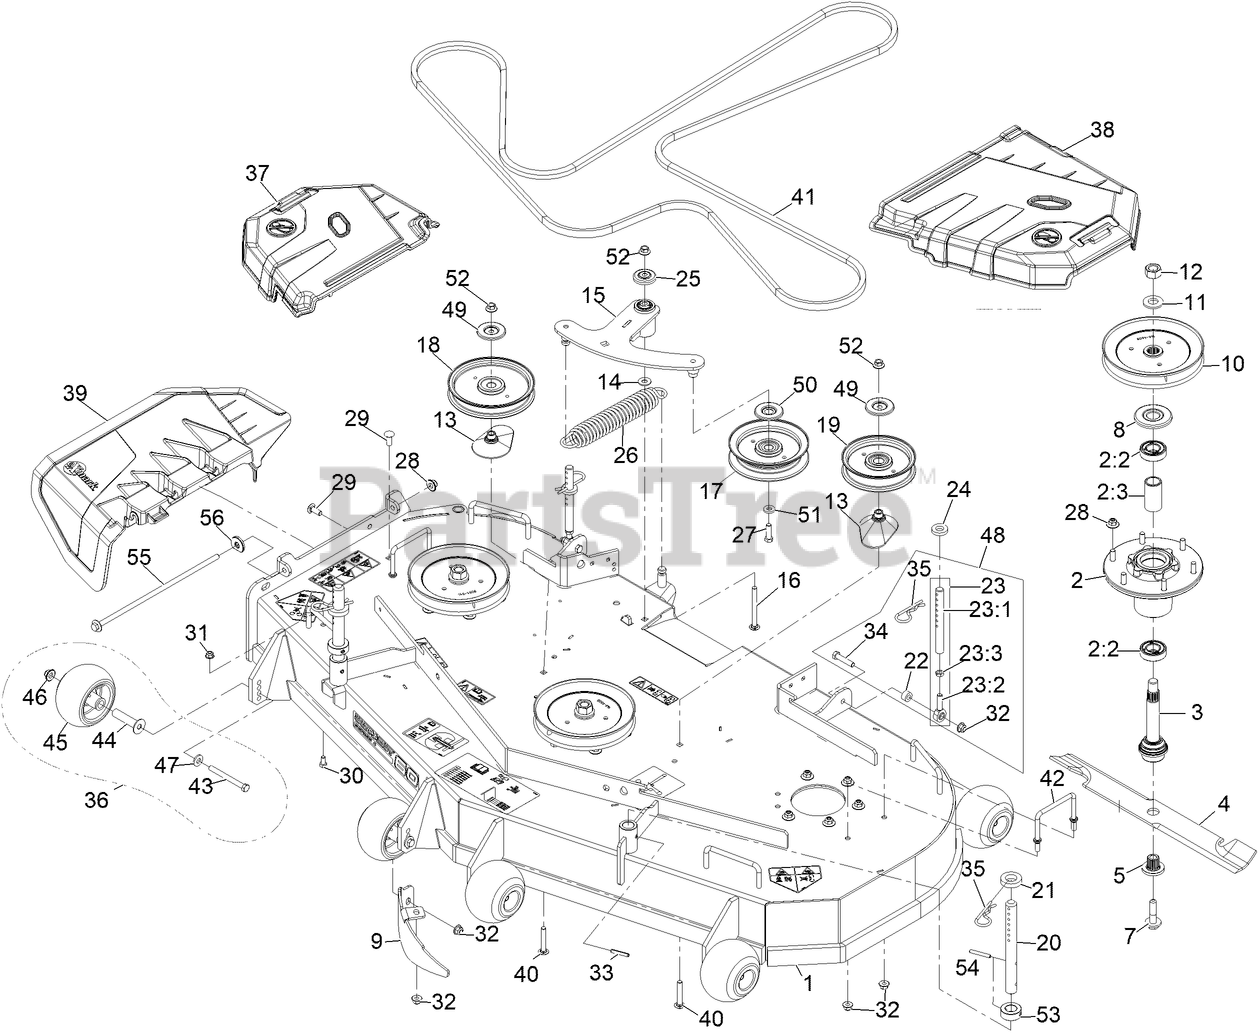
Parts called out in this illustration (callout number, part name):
1	ASM, Deck W/ Decals, 60"
2	ASM-CUTTER HSG WITH BEARINGS
2:2	BEARING-BALL
2:3	SPACER-BEARING
3	ASM-SPINDLE AND SEAL
4	Blade-Extreme 2, 20.50"
5	BUSHING,SPLINED
7	SCREW,SEMS 1/2-20 X 2.19
8	GUARD,BEARING TOP .989
9	DOGLEG - LZ60
10	SHEAVE,BLADE DRIVE 7.25
12	NUT-HEX
13	SPACER-PULLEY
14	WASHER-FLAT
15	ASM, DECK IDLER
16	SCREW-CARR
17	IDLER-PULLEY, FLAT
18	Idler-Pulley, Flat
19	Pulley-Idler, Flat
20	ROD, DECK SUPPORT
21	SPACER-DECK SUPPORT
23:1	LINK,SUPPORT
23:2	BALLJOINT
23:3	NUT-HJ
25	GUARD-TOP
26	SPRING-EXTENSION
27	SCREW-HH
28	Nut-Nyloc 3/8-16 Flg
29	SCREW-CARR
30	SCREW-HH
31	NUT-HF, NI
32	NUT-HF, NI
34	SCREW-HH
35	PIN,HAIR COTTER
36	KIT, ANTI-SCALP ROLLER
37	SHIELD, RT
38	SHIELD, LT
39	Chute-Deck Discharge
40	BOLT-CARR, SHORT NECK
42	WIREFORM-COVER
43	SCREW-HH 3/8-16 X 3 3/4 GR 8
44	AXLE, ROLLER
45	ROLLER-SCALP, ANTI
46	Nut-Nyloc 3/8-16 Flg
47	WASHER-BELLEVILLE
48	KIT,SUPPORT LINK W/PIN
49	SHIELD-DUST
50	SHIELD-GUARD, DUST
53	COLLAR, DECK HEIGHT PIN
54	PIN-ROLL
55	Pin, Chute
56	Retainer, Chute
